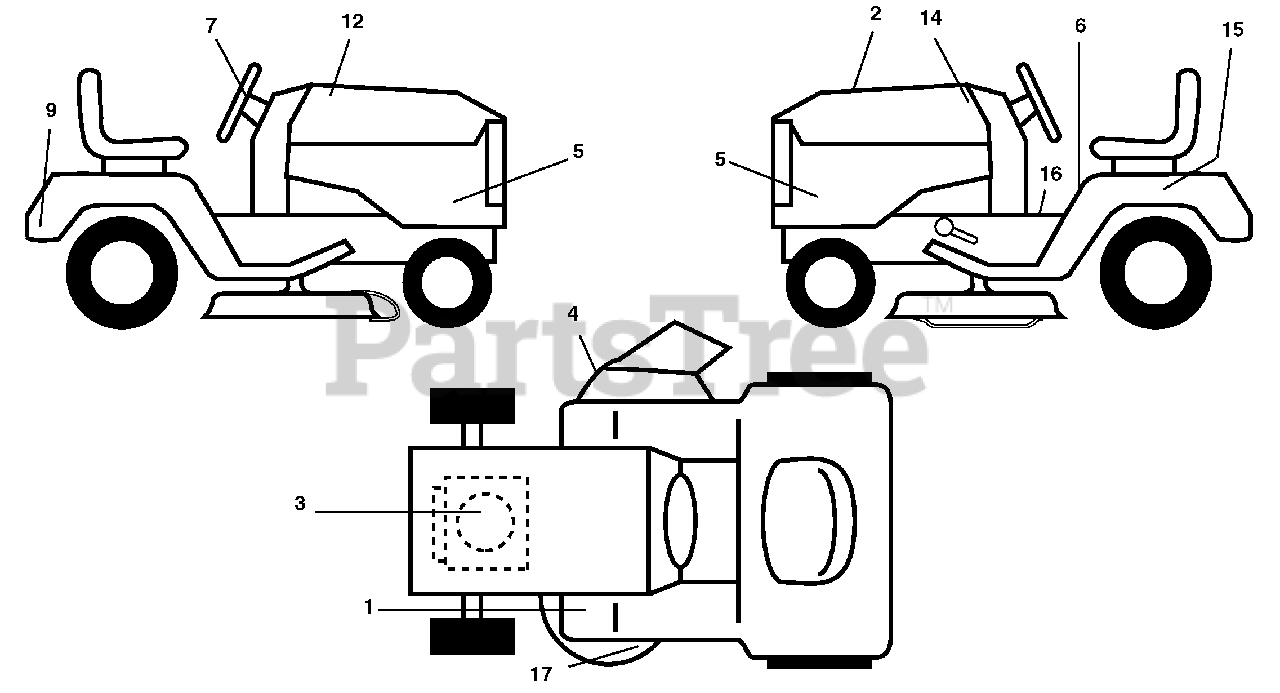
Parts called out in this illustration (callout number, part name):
1	Decal, Clutch Brake
2	Decal, Replacement
3	Decal, Engine HP
4	Decal Warning
5	Decal, SDPNL
6	Decal, Fender Danger English
7	Decal Ins Str Wh
9	Decal Fender
12	Decal, Hood RH
14	Decal, Hood LH
15	Decal, Caution, Battery
16	Decal, Oper Sdl P/L Gear Dr Eng
17	Decal, V-Belt Sch.
17	Decal, Handle Lft Height Adj.
17	Manual, Operator's E&F
17	Manual, Parts E&F
